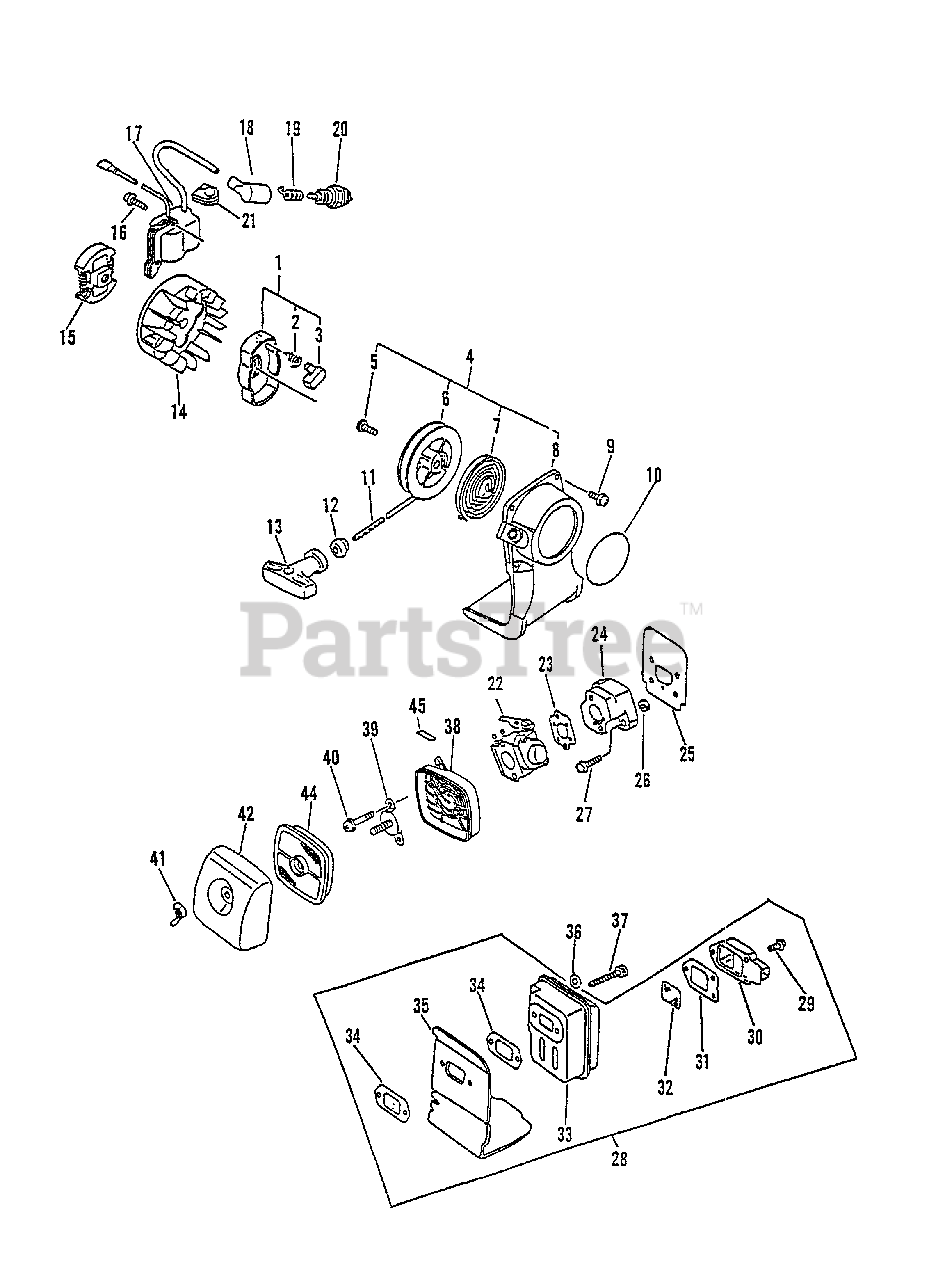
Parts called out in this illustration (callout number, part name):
1	PAWL ASSY, STARTER
2	SPRING, RETURN
3	PAWL, STARTER - BLACK
4	STARTER ASSY
5	SCREW
6	REEL, ROPE
7	SPRING, RECOIL
8	CASE, RECOIL STARTER
9	SCREW 4×16
11	ROPE, STARTER
12	GUIDE, ROPE
13	GRIP, STARTER
14	FLYWHEEL
15	CLUTCH ASSY
16	SCREW 4×22
17	COIL, IGNITION
18	CAP, SPARK PLUG
19	TERMINAL, SPARK PLUG
20	SPARK PLUG - BPM7A
22	CARBURETOR - C1U-K16
23	GASKET, INTAKE
24	INSULATOR, INTAKE
25	HEAT SHIELD, INTAKE
26	NUT M5
27	SCREW 5×20
28	MUFFLER ASSY
29	SCREW 4×10
30	GUIDE, EXHAUST - INNER
31	GASKET, EXHAUST
32	SCREEN, SPARK ARRESTER
33	MUFFLER
34	GASKET, EXHAUST
35	COVER, EXHAUST
36	WASHER, FLAT 5.5×10×0.8
37	BOLT 5×55
38	CASE ASSY, AIR FILTER
39	PLATE, PREVENT
40	SCREW 5×65
41	WINGNUT - 6
42	COVER, AIR FILTER
43	LABEL - TOP
44	FILTER, AIR
45	LABEL, CHOKE
